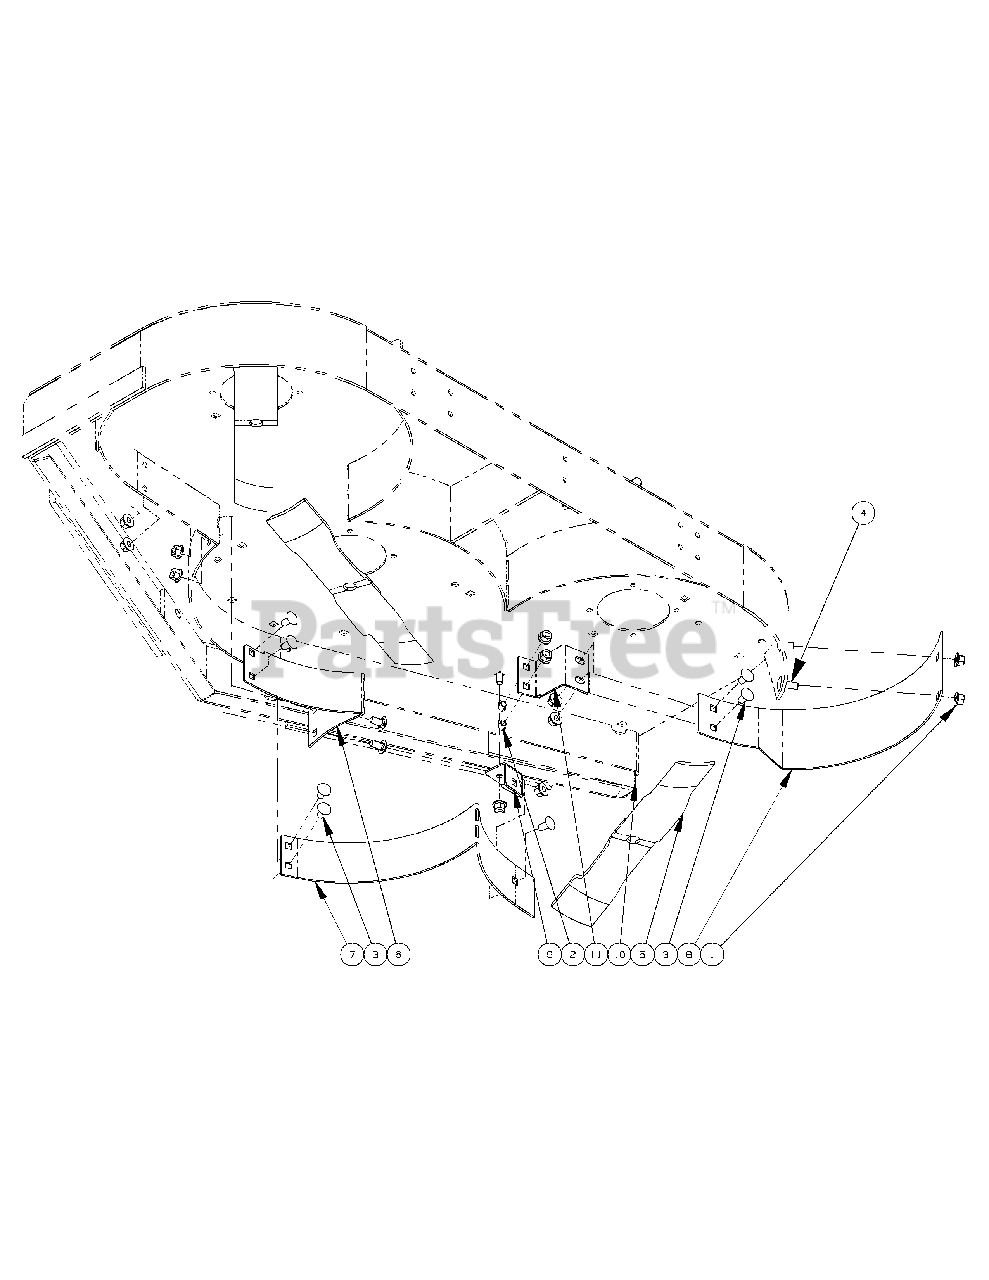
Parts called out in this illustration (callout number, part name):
1	Flange Lock Hex Nut, 3/8-16
2	HHCS, 3/8-16 x .88
3	Carriage Bolt, 3/8-16 x .75
4	Carriage Bolt, 3/8-16 x 1.0
5	Blade, Mulch 17.0, 0.756 ID
6	Mulching Baffle, LH
7	Mulching Baffle, Center
8	Mulching Baffle, RH
9	Mulching Bracket, Center
10	Mulch Plug Baffle
11	Mulching Bracket, RH
